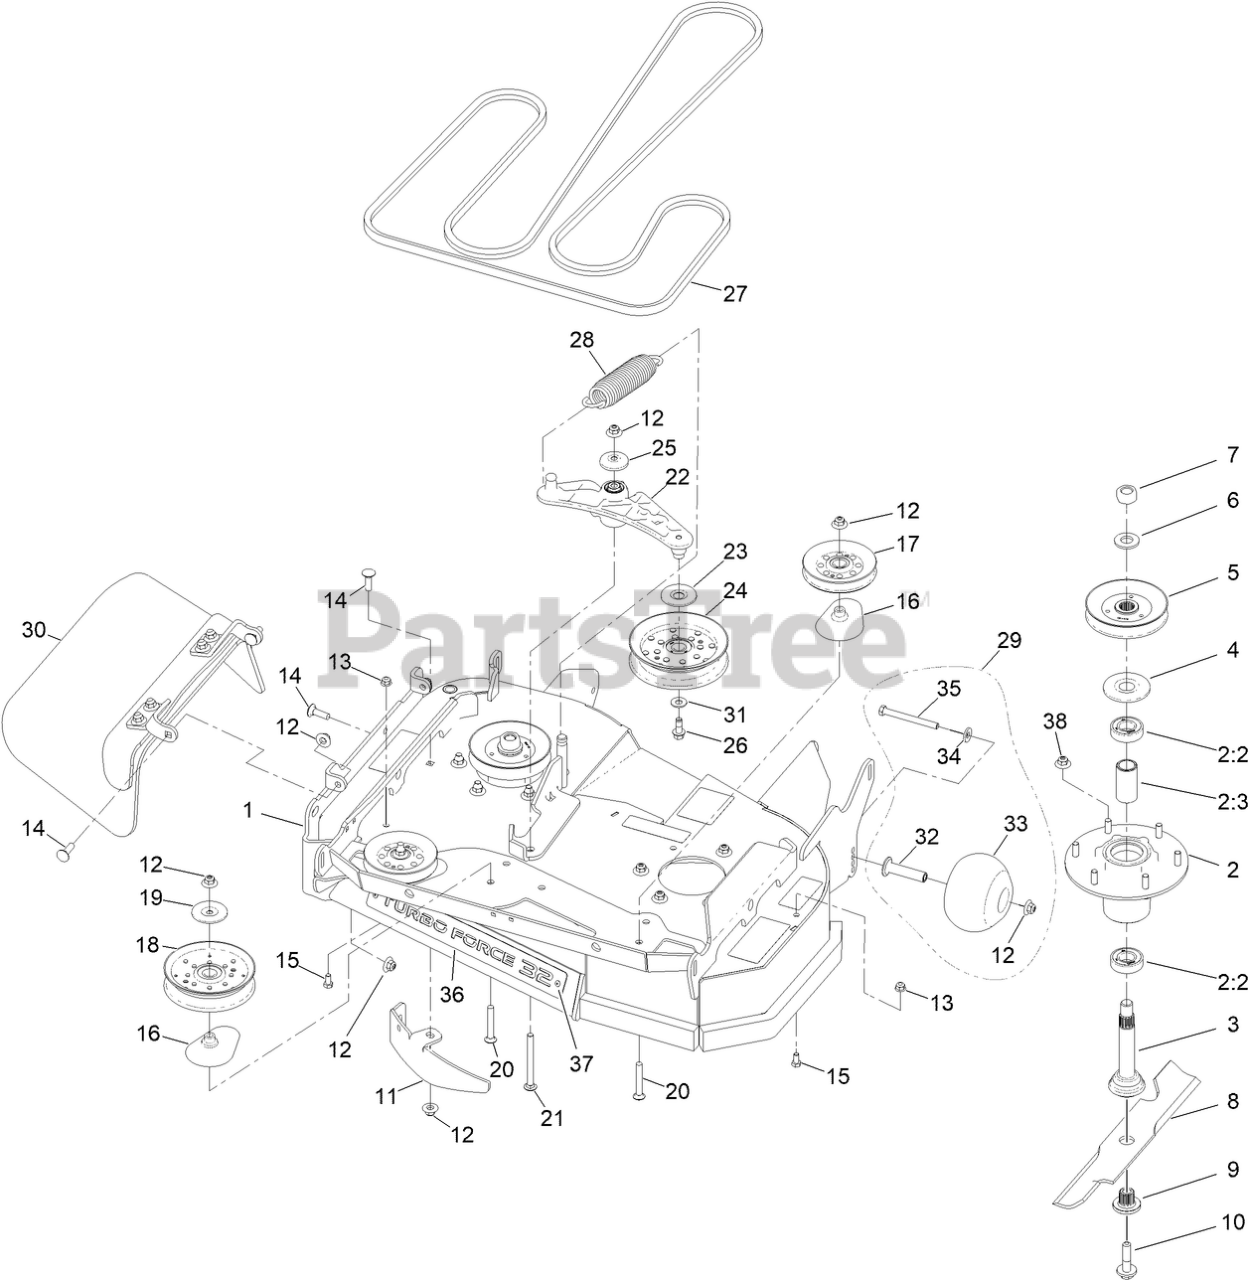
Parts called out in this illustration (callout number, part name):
1	ASM 32 DECK
1	ASM-DECK W/DECALS
2	ASM-CUTTER HSG WITH BEARINGS
2:2	BEARING-BALL
2:3	SPACER-BEARING
3	ASM-SPINDLE AND SEAL
4	GUARD,BEARING TOP .989
5	SHEAVE-BLADE DRIVE
6	WASHER
7	NUT-HEX
8	BLADE-HIGH FLOW
9	Bushing, Splined
10	SCREW-SEMS
11	BAFFLE, DOGLEG
12	NUT-FLANGE, NI
13	NUT-HF, NI
14	BOLT-CARR
15	SCREW-HH
16	SPACER-PULLEY
17	IDLER - V 4.13 EOD-A
18	PULLEY-IDLER, FLAT
19	SHIELD-DUST
20	SCREW-CARR
21	SCREW-CARR
22	ASM.-ARM, IDLER
23	SHIELD-GUARD, DUST
24	IDLER-PULLEY, FLAT
25	GUARD-TOP
26	SCREW-HFH
27	BELT-V
28	SPRING-EXTENSION
29	KIT, ANTI-SCALP ROLLER
30	RUBBER DEFLECTOR ASM
31	WASHER-FLAT
32	AXLE, ROLLER
33	ROLLER-SCALP, ANTI
34	WASHER-BELLEVILLE
35	SCREW-HH
36	PLATE-BADGE [BLACK]
37	RIVET-TRIFOLD
38	NUT-HF, NI
